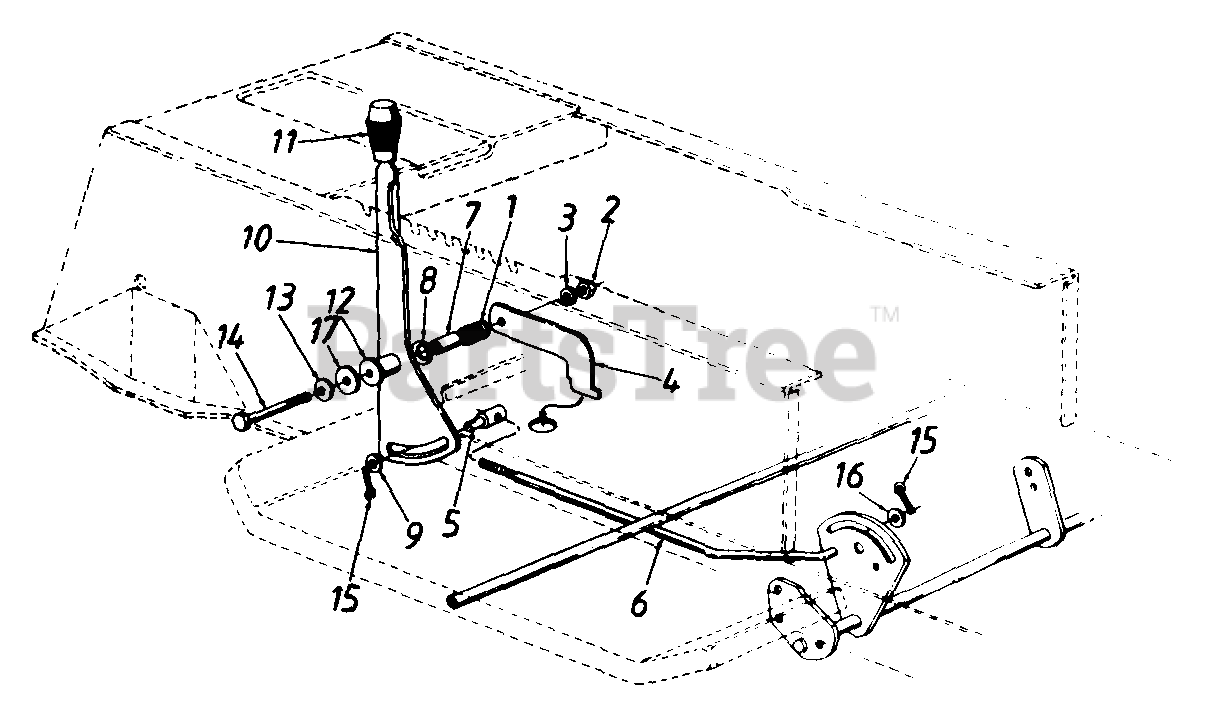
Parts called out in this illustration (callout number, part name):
1	Compression Spring
2	Hex Nut 5/16-18 Thd.
3	L-Wash. 5/16" I.D.
4	Shift Lever Support
5	Ferrule 3/8-24 Thd.
6	Speed Control Rod
7	Spacer 1.15" Lg.
8	Bell-Wash..505" I.D. x 1"
9	Fl-Wash..385" I.D. x .87"
10	Speed Selector Lever
11	Shift Knob
12	Spacer 1.46" Lg.
13	Bell-Wash..345" I.D. x .88"
14	Hex Bolt 5/16-18 x 3.25" Lg.
15	Cotter Pin 3/32" Dia. x 1"
16	Fl-Wash..469" I.D. x .88"
17	Fl-Wash..34" I.D. x 2.25"
